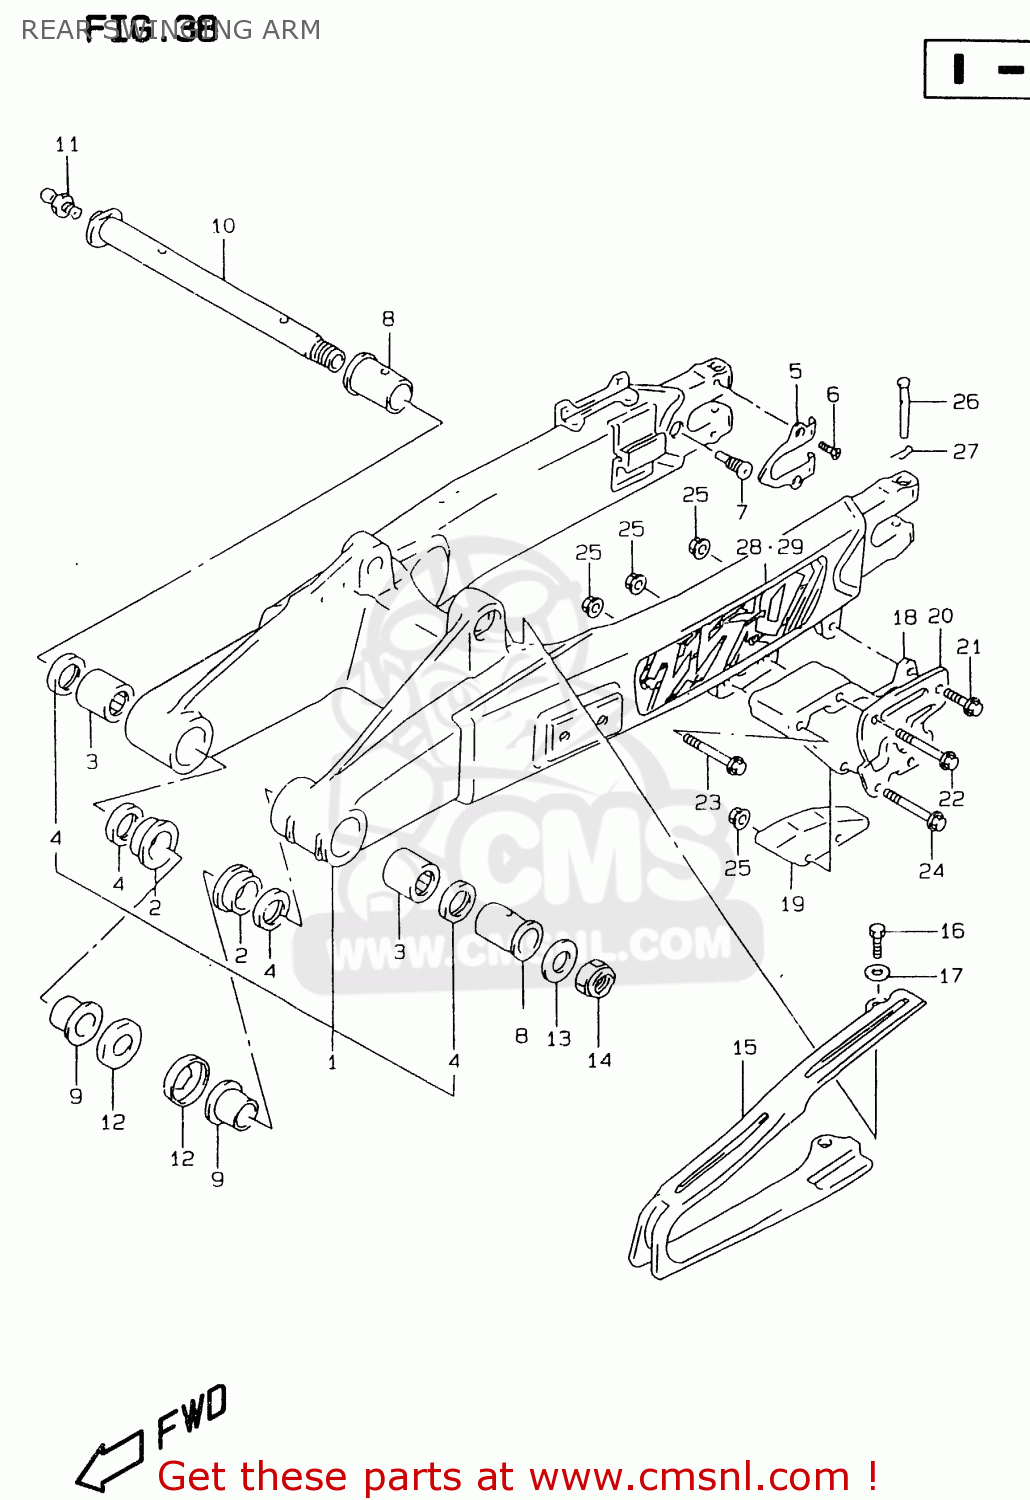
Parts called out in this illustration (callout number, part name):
1	SWING ARM ASSEMBLY,REAR
2	BUSHING,SWGARM PIVOT
3	BEARING(22X29X30)
4	SEAL,OIL(22X29X4)
5	PLATE,RR SWING ARM AXLE
6	SCREW(5X8)
7	SCREW (M10X21)
8	SPACER,RR SWGARM PIVOT
9	SPACER,SWGARM PIVOT INNER
10	SHAFT SET,SWING ARM
11	NIPPLE
12	COVER,SWINGINGARM PIVOT
13	WASHER, FIXED DRIVE FACE
14	NUT
15	BUFFER,CHAIN TOUCH DEFENSE
16	BOLT
17	WASHER
18	GUIDE,CHAIN
19	DEFENSE,CHAIN GUIDE
20	PLATE,CHAIN GUIDE OUTER
21	BOLT,G/S SWITC
22	BOLT
23	BOLT
24	BOLT
25	NUT
26	PIN
27	CLIP
28	EMBLEM,SWING ARM
29	EMBLEM,SWING ARM,LEFT
